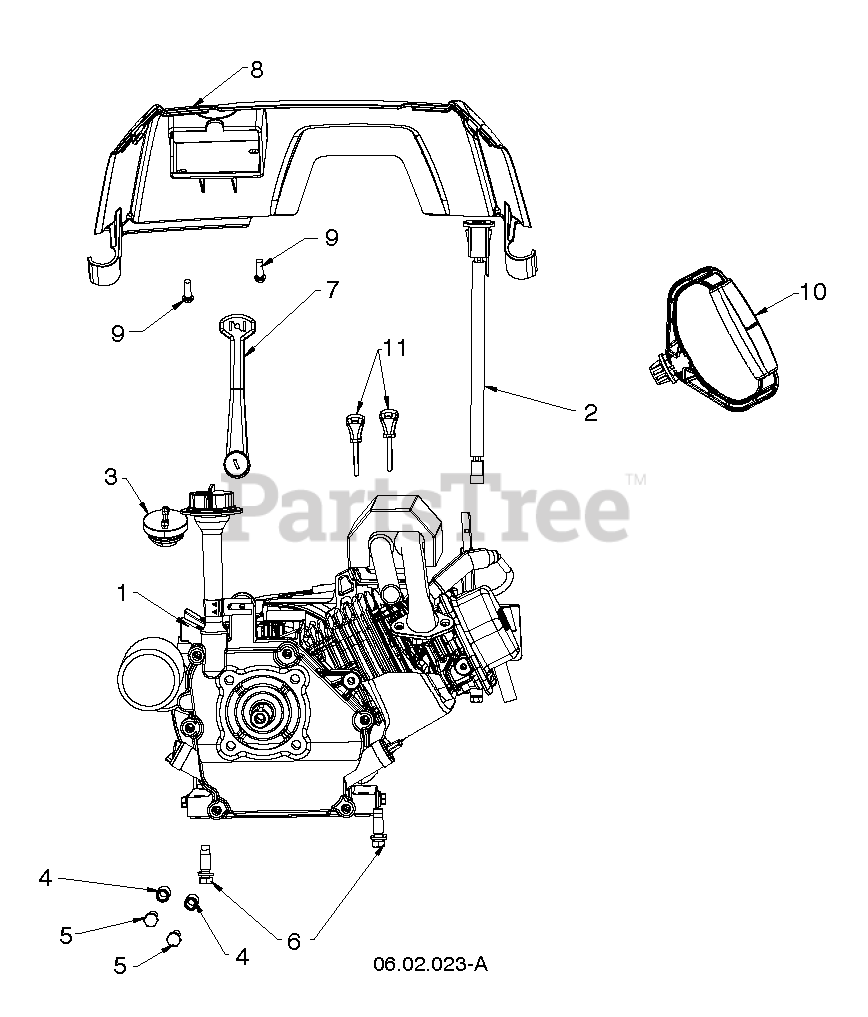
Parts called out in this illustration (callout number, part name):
1	ENGINE.LCT.208CC.ESTART.W/ALT
2	SWITCH.KEY.SST.SNOW
3	RP BULB.PRIMER
4	SPACER.ENGINE
5	SCREW. 5/16-24 X 2.00"HHCS
6	BOLT 3/8-16X1-1/8
7	LEVER.CHOKE
8	COVER.REAR.LOWER.SSST.HUSQ.GRE
9	SCREW.HX.13X.750
10	HANDLE.STARTER.SNOW
11	KEY SET(2 KEYS) SKSN0407.1
